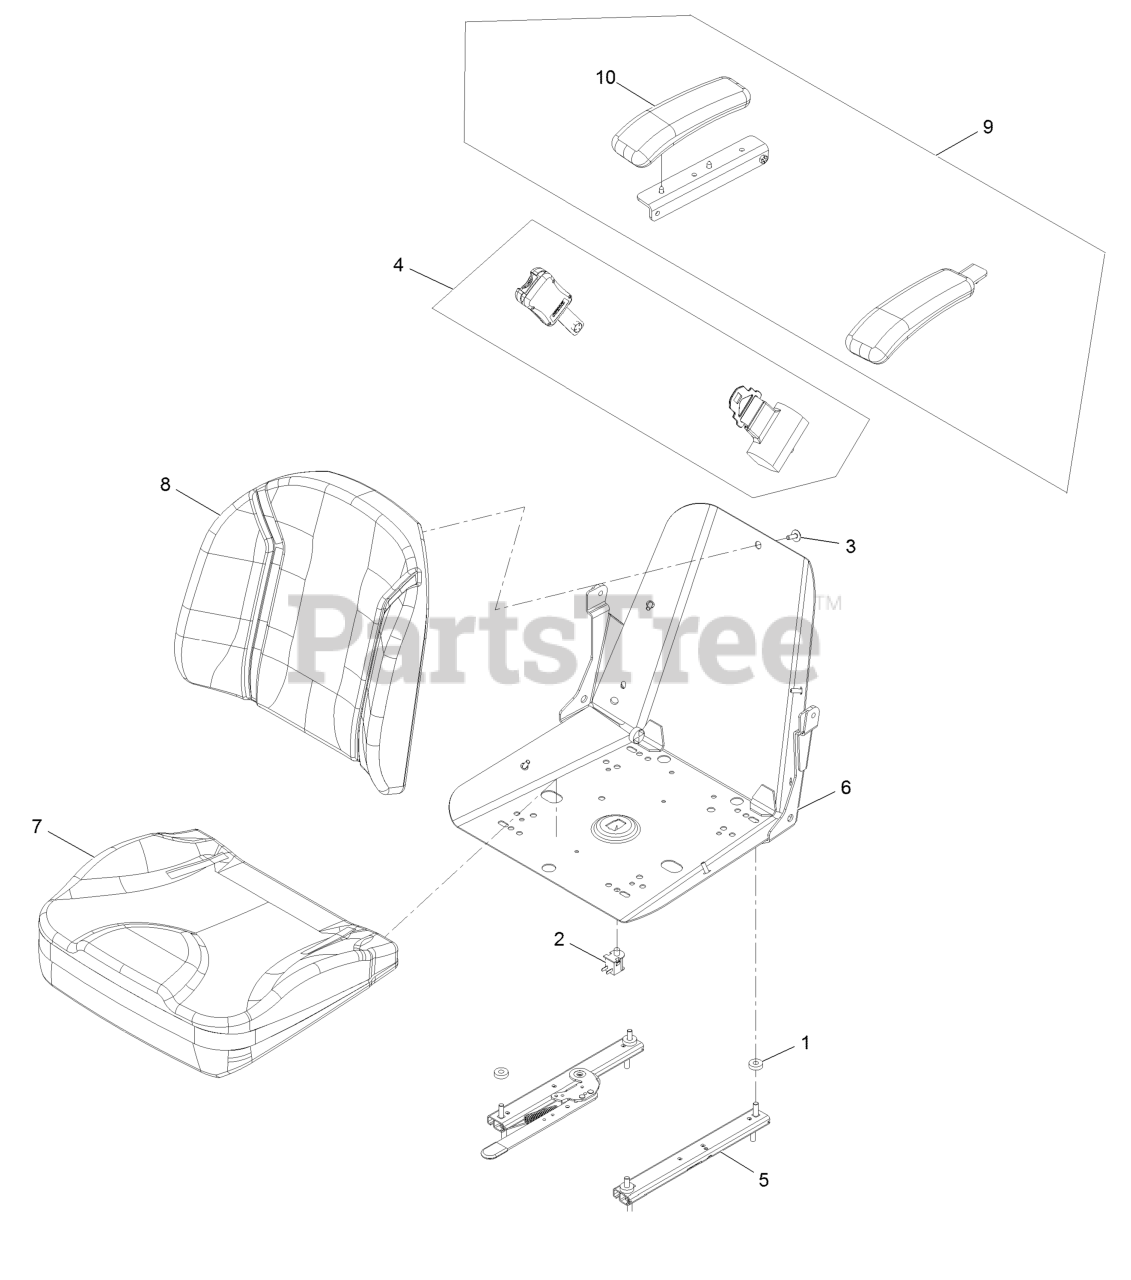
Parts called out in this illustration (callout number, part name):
1	Spacer-Pin, Mounting
3	Screw-HWH 1/4-20 X 3/4 Taptite
4	Kit-Seat Belt
5	ASM-Seat Track Svc
6	Frame-Seat Svc
7	Cover-Seat Bottom Svc
8	Cushion-Seat, Back
9	Armrest Kit
10	Cushion-Rest, Arm
